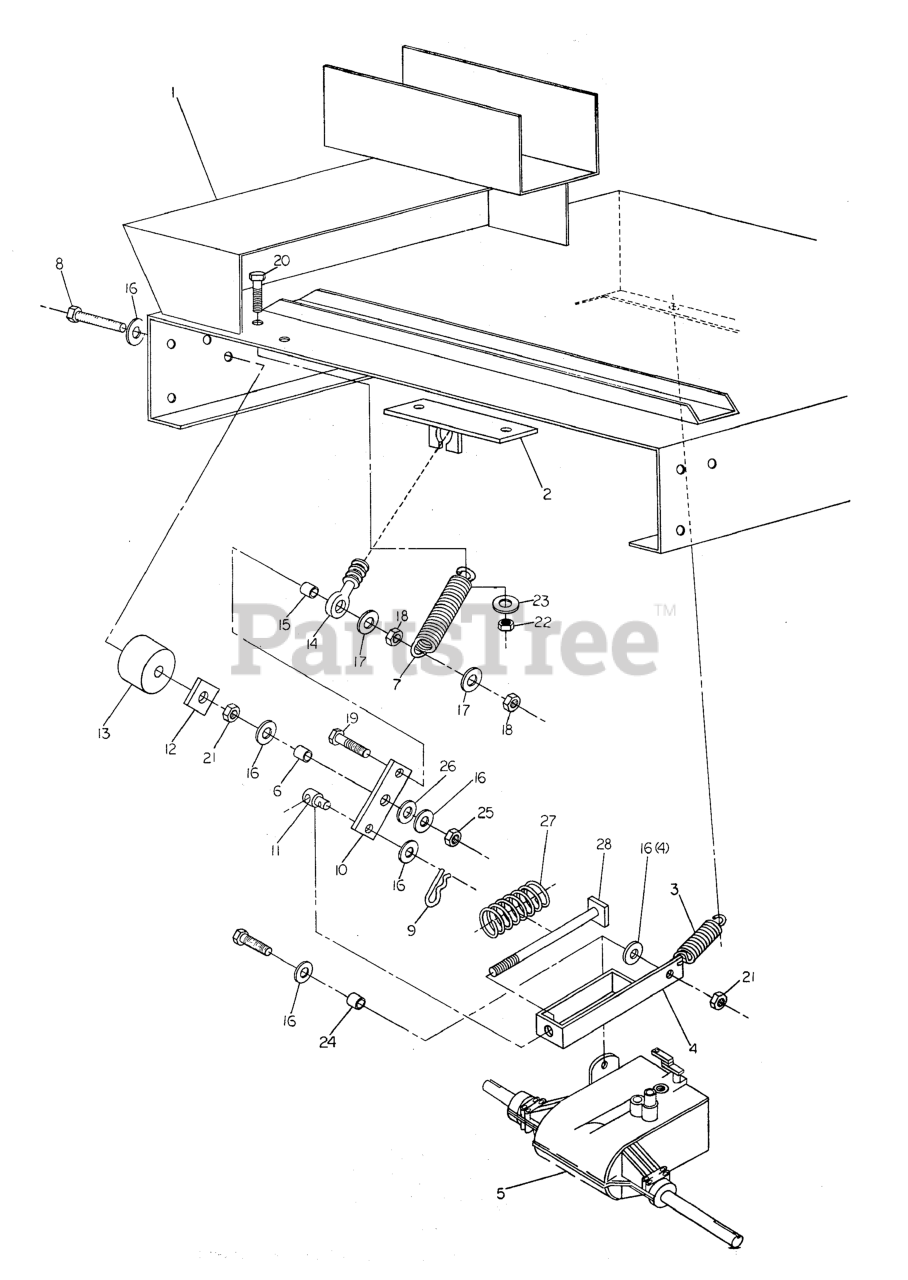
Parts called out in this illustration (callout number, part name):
1	Engine Deck Weldment
2	Brake Cable Mount Weldment
3	SPRING, Extension
4	Brake Weldment
5	Transaxle
7	SPRING, Extension
8	3/8-16 x 3-1/2 GD 5 Tap Bolt
9	HAIRPIN CLIP
10	Brake Lever
11	Brake Linkage Adjuster
12	Brake Mount
13	Nylon Roller
14	Clutch Cable
15	Cable Spacer
16	3/8 Flat Washer SAE
17	1/4 Flat Washer
18	1/4-20 Lock Nut
19	1/4-20 x 1-1/2 GD 5 Bolt
20	5/16-18 x 1-1/4 GD 5 Tap Bolt
21	3/8-16 Serrated Flange Nut
22	5/16-18 Lock Nut
23	5/16 Flat Washer
24	SLEEVE
25	3/8-16 Top Lock Nut
26	1/2 Flat Washer SAE
27	SPRING, Compression
28	Brake Linkage Adjustment Rod
